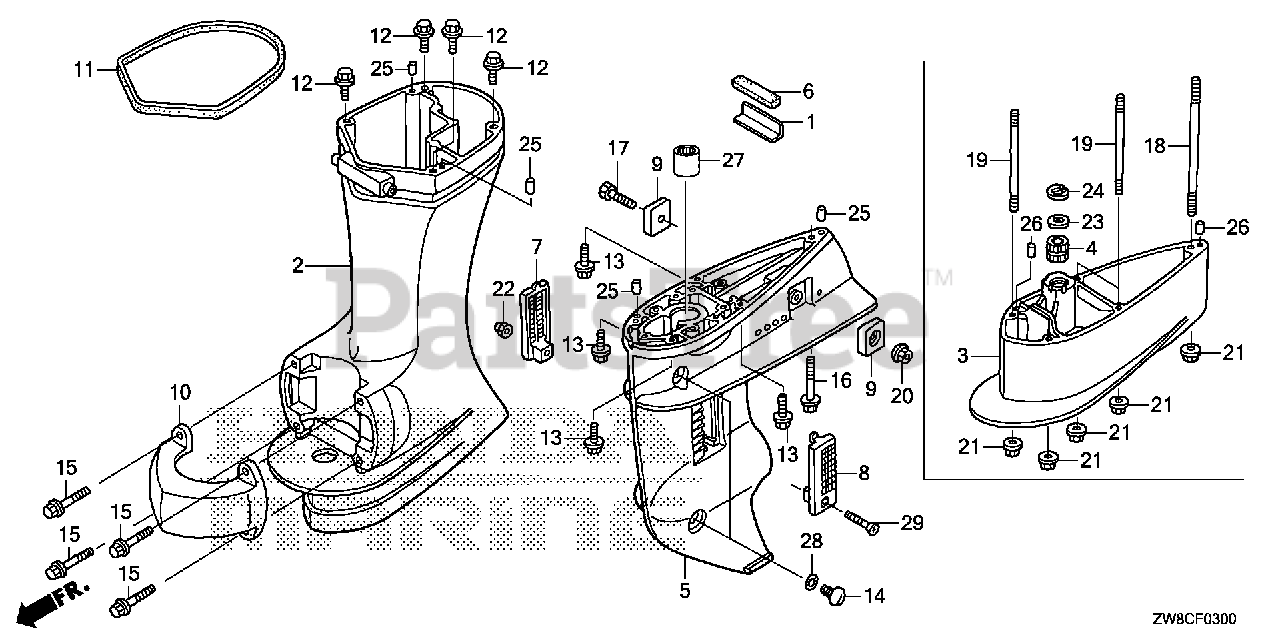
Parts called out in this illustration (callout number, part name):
1	PLATE, RUBBER SETTING
2	CASE, EXTENSION *NHB14M* (S) (AQUA MARINE SILVER METALLIC)
5	CASE, GEAR *NHB14M* (AQUA MARINE SILVER METALLIC)
6	GROMMET, GEAR CASE
7	SCREEN, R WATER
8	SCREEN, L. WATER
9	METAL, ANODE
10	HOUSING, MOUNTING (LOWER) *NHB14M* (AQUA MARINE SILVER METALLIC)
11	RUBBER, COVER (LOWER)
12	BOLT, FLANGE (8X35)
13	BOLT, FLANGE (6X23)
14	BOLT, OIL CHECK
15	BOLT, FLANGE (6X20)
16	BOLT, FLANGE (6X75)
17	BOLT, HEX. (6X25)
20	NUT, SELF-LOCK (6MM)
22	NUT, SELF-LOCK (5MM)
25	PIN, DOWEL (6X10)
27	BUSH, PINION GEAR
28	O-RING (6.9X1.45)
29	SCREW, OVAL (5X28)
